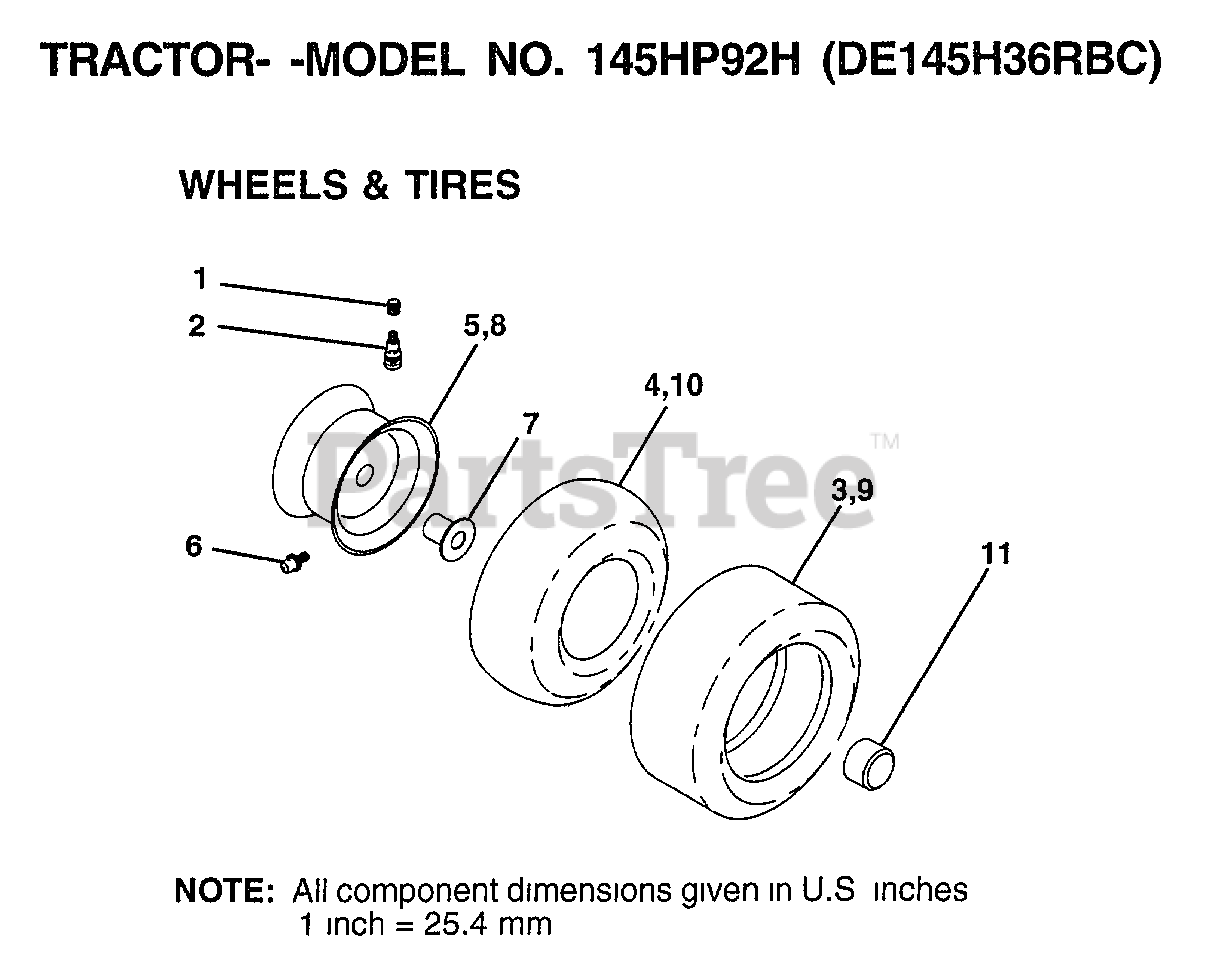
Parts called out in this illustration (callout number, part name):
1	VALVE CAP
2	VALVE STEM LT
4	TUBE.5.3/4.5/6
5	"RIM,FRT T"
6	FITTING LT
7	"FLANGE, BEARING"
8	"RIM 8"""
9	TIRE.20X8-8
10	TUBE.18X9.5-8
11	HUB CAP
